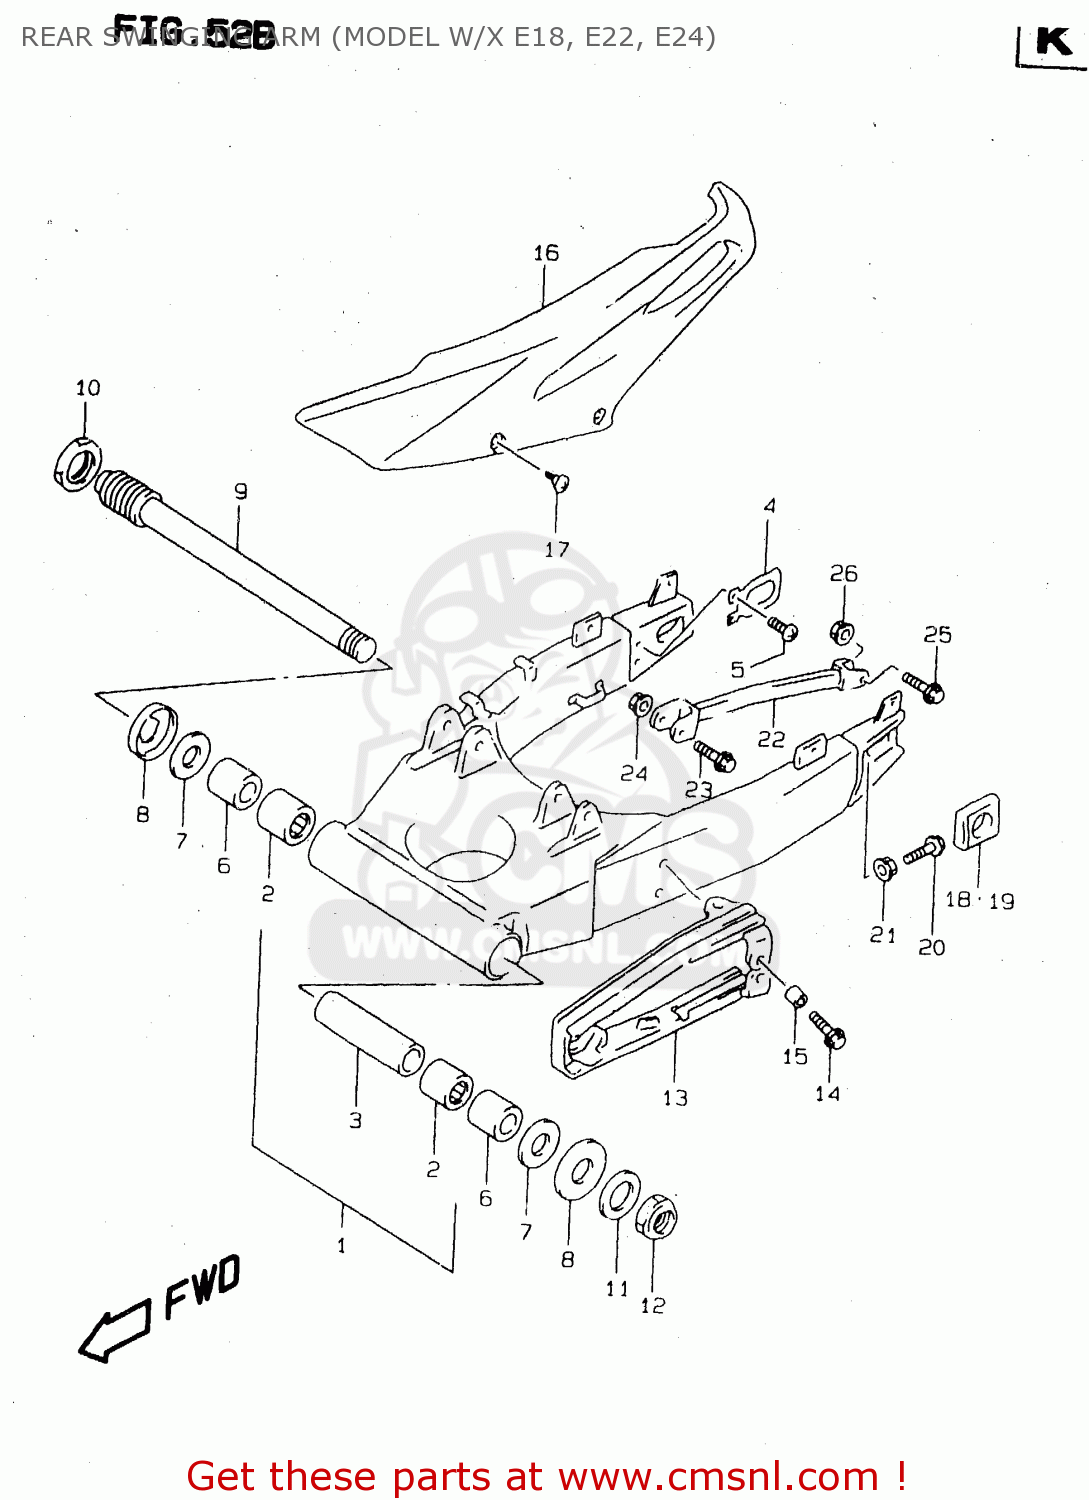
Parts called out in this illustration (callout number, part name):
1	SWINGINGARM ASSY,RR
2	BEARING(30X40X25)
3	SPACER COMP,REAR SWING PIVOT
4	PLATE,RR SWING ARM BRKT
5	SCREW 6X10
6	SPACER,REAR SWING ARM PIVOT
7	WASHER
8	DUST SEAL,RR SWGARM PIVOT
9	SHAFT,RR SWINGINGARM PIVOT
10	NUT,REAR SWING ARM PIVOT
11	WASHER(25.2X42X3.2)
12	NUT
13	BUFFER,CHAIN TOUCH DEFENSE
14	BOLT 6X20,WITH PLAIN WASHER
15	SPACER(6.5X9X5)
16	CASE, CHAIN
17	SCREW (6X14)
18	ADJUSTER,CHAIN,R
19	ADJUSTER,CHAIN,L
20	BOLT(8X50)
21	NUT
22	TORQUELINK,RR
23	BOLT(8X44)
24	NUT
25	BOLT(10X37)
26	NUT
